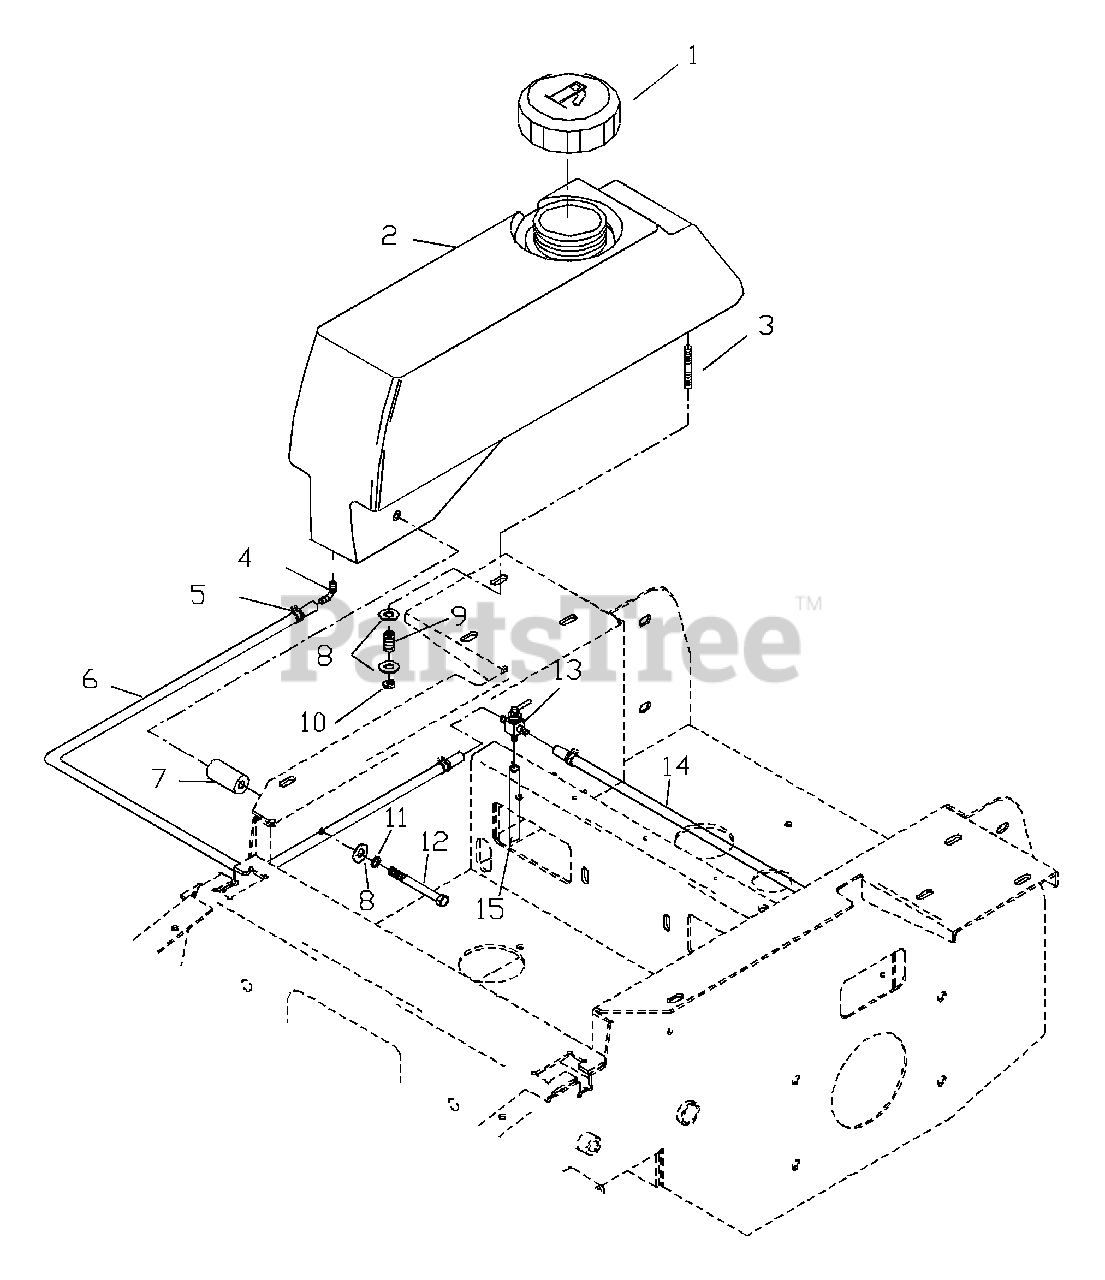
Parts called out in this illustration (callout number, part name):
1	FUEL CAP
2	RT. FUEL TANK
2	LT. FUEL TANK
4	90 DEG. HOSE BARB
5	HOSE CLAMP
6	FUEL LINE 30" (2 ON KAW.)
7	TANK SPACER
8	5/16 FLAT WASHER
10	5/16C LOCKNUT
11	5/16 LOCK WASHER
12	HCS 5/16C X 4
13	FUEL VALVE
14	FUEL LINE 41"
15	FUEL LINE 16" (KOHLER)
